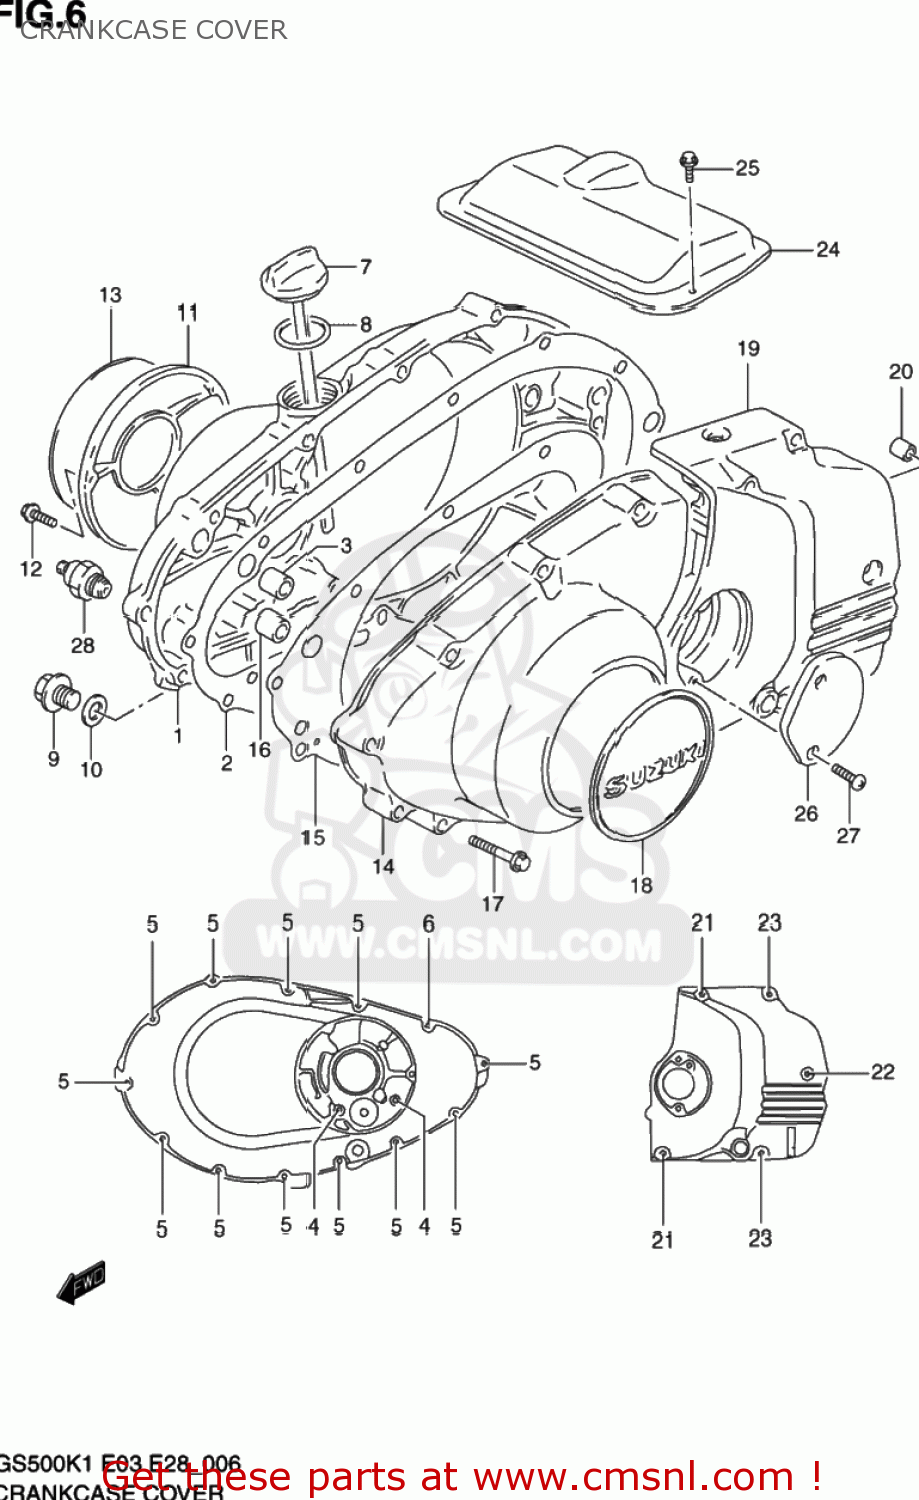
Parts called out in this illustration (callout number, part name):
1	COVER,CLUTCH
2	GASKET,CLUTCH COVER (NAS)
3	PIN
4	BOLT(6X55)
5	BOLT(6X35)
6	BOLT(6X55)
7	GAUGE,OIL LEVEL
8	O RING(D:3.1,ID:26.4)
9	PLUG (14X12)
10	GASKET(13.8X18.8X4.8) (NAS)
11	COVER,CONTACT BREAKER
12	BOLT(5X16)
13	EMBLEM,CONTACT BREAKER COVER
14	COVER,MAGNETO
15	GASKET,MAGNETO COVER (NAS)
16	PIN
17	BOLT(6X35)
18	EMBLEM,CONTACT BREAKER COVER
19	COVER,ENGINE SPROCKET
20	PIN
21	BOLT(6X65)
22	BOLT(6X50)
23	BOLT(6X40)
24	COVER,STARTER MOTOR
25	BOLT
26	CAP,CLUTCH RELEASE ADJUST
27	SCREW
28	SWITCH ASSY,OIL PRESSURE
